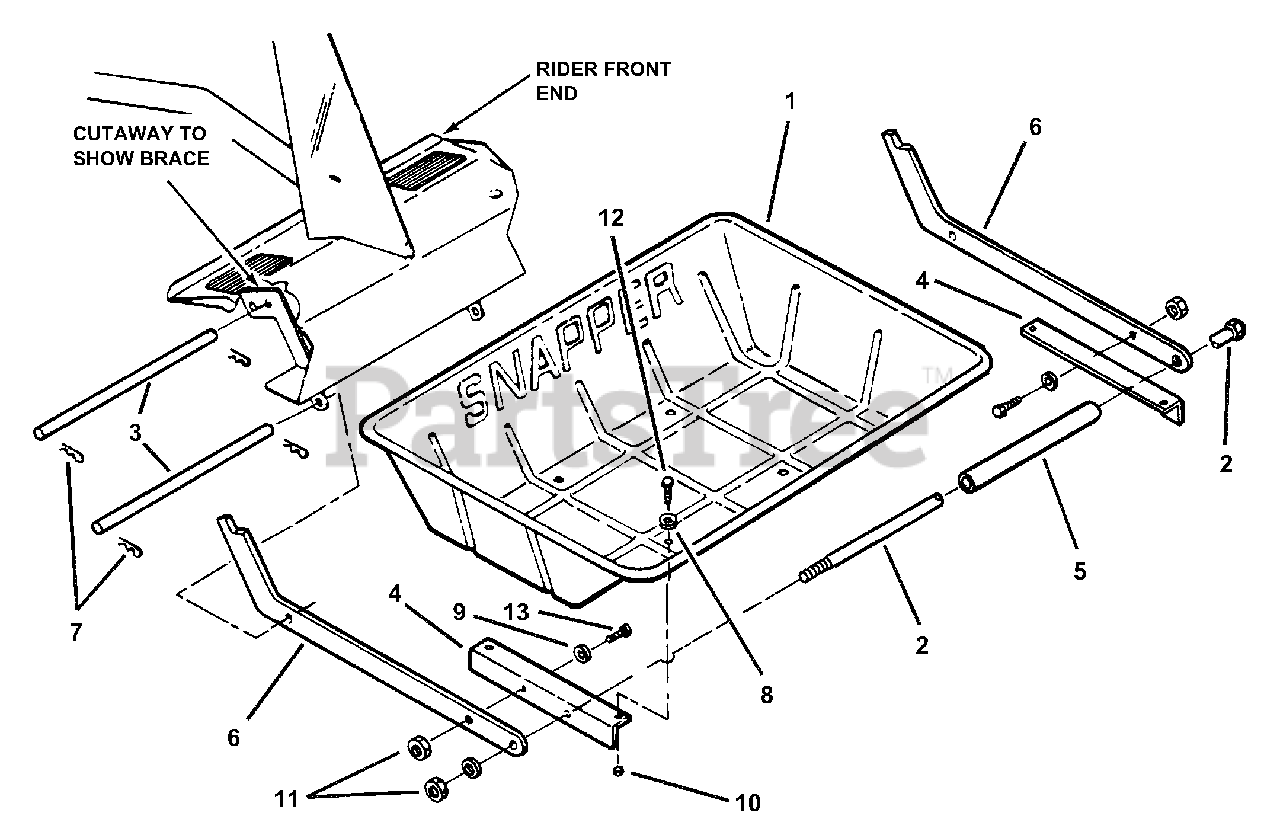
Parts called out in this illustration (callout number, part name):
1	BOX, Tote (18" x 24" x 5")
2	BOLT, 3/8-16 x 10" Hex
3	PIN, Holding
5	SPACER, Box
6	ARM
7	HAIR PIN, 3/32 x 1-7/8"
8	WASHER, 1/4" Flat
9	WASHER, 3/8" Flat
10	NUT, 1/4-28 Hex Top Lock
11	NUT, 3/8-16 Hex Top Lock
12	SCREW, 1/4-28 x 3/4" Hex Head Cap
13	SCREW, 3/8-16 x 1" Hex Head Cap
